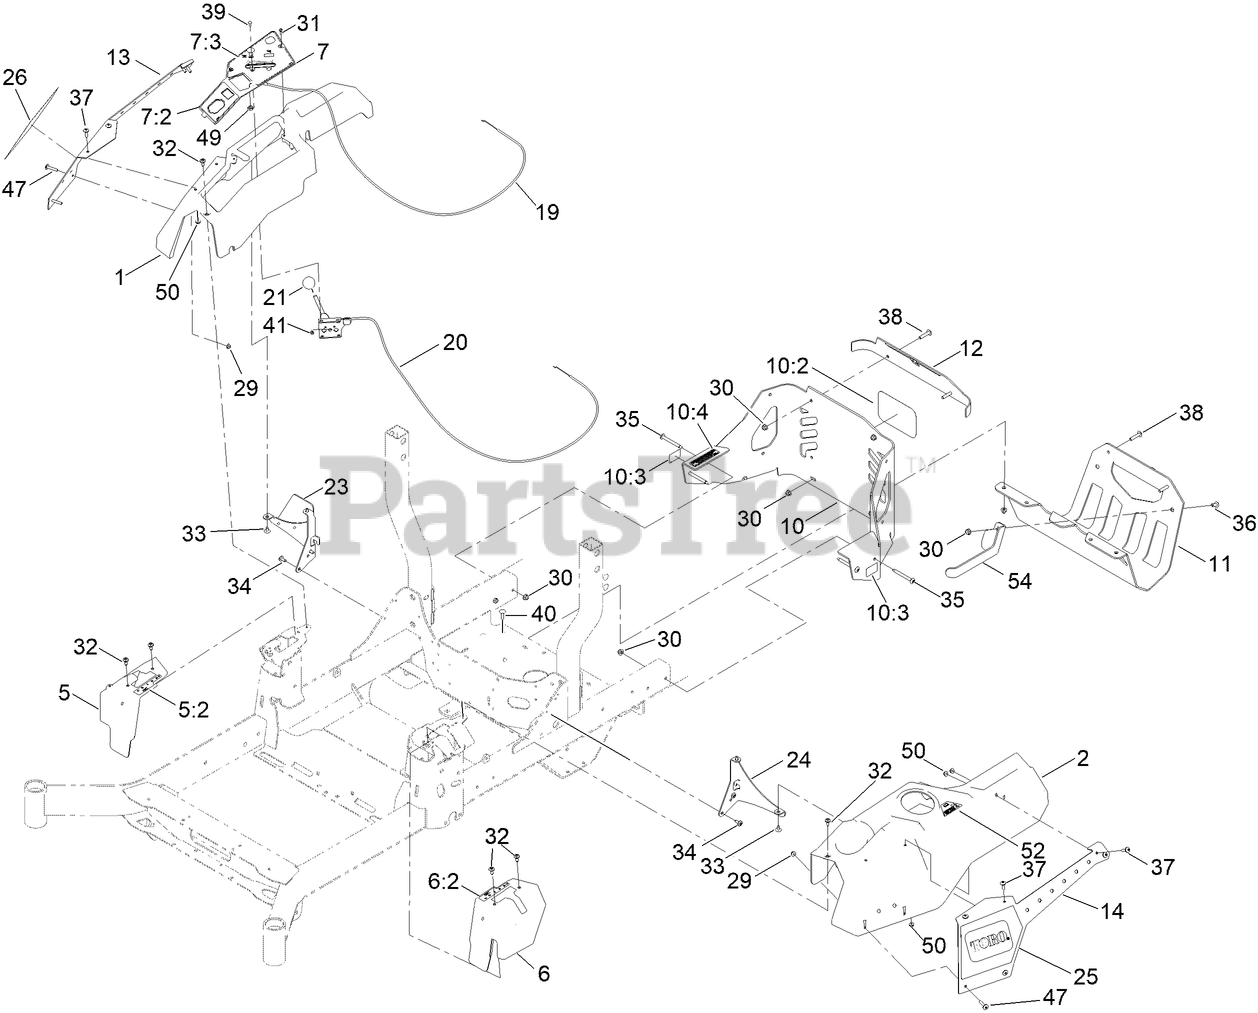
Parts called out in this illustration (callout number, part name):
1	CONSOLE-RH
2	CONSOLE-LH
5	COVER-CONTROL, MOTION (RH)
5:2	DECAL-CONTROL, MOTION (RH)
6	COVER-CONTROL, MOTION (LH)
6:2	DECAL-CONTROL, MOTION (LH)
7	CONTROL PANEL ASM
7:2	DECAL-PANEL, CONTROL
7:3	DECAL-PANEL, CONTROL
10	REAR GUARD ASM
10:2	DECAL
10:3	DECAL-WARNING
10:4	DECAL-ARRESTOR, SPARK
11	GUARD-MUFFLER [BLACK]
12	TRIM-UPPER REAR
13	COVER-POD, RH
14	COVER-LH
19	CABLE-CONTROL, CHOKE
20	CABLE-CONTROL, THROTTLE
21	KNOB-BALL
23	SUPPORT-CONSOLE, RH
24	BRACKET-CONSOLE, LH
25	DECAL-PLATE, LH
26	DECAL-PLATE, RH
29	NUT-HF
30	NUT-HF, NI
31	SCREW-HWH
32	SCREW-SHOULDER
33	SCREW-TORX
34	SCREW-TORX
35	SCREW-TORX
36	SCREW-TORX
37	SCREW-TRUSS
38	SCREW-TORX
39	BOLT-CARR
40	SCREW-CARR
41	NUT-LOCK, NI
47	SCREW-TRUSS
49	NUT-HJ
50	NUT-KEPS
52	DECAL-FILL, FUEL
54	BRACKET-GUARD, MUFFLER
